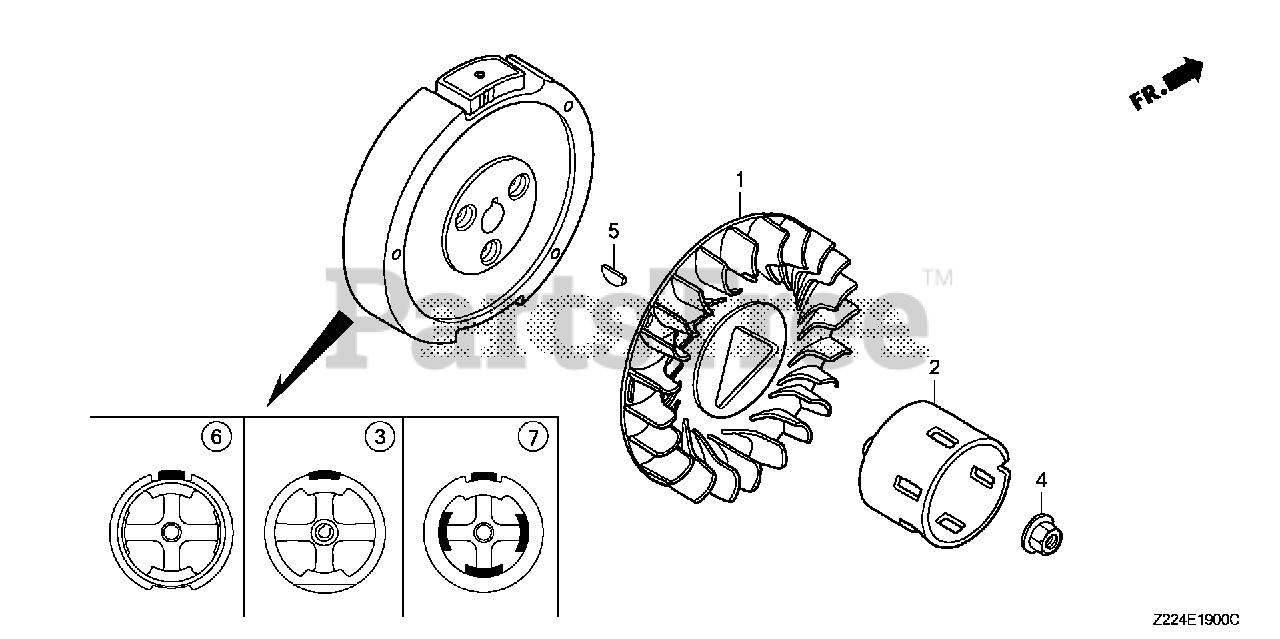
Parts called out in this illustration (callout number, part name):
1	FAN, COOLING
2	PULLEY, STARTER
4	NUT, SPECIAL (16MM)
5	KEY, SPECIAL WOODRUFF (25X18)
